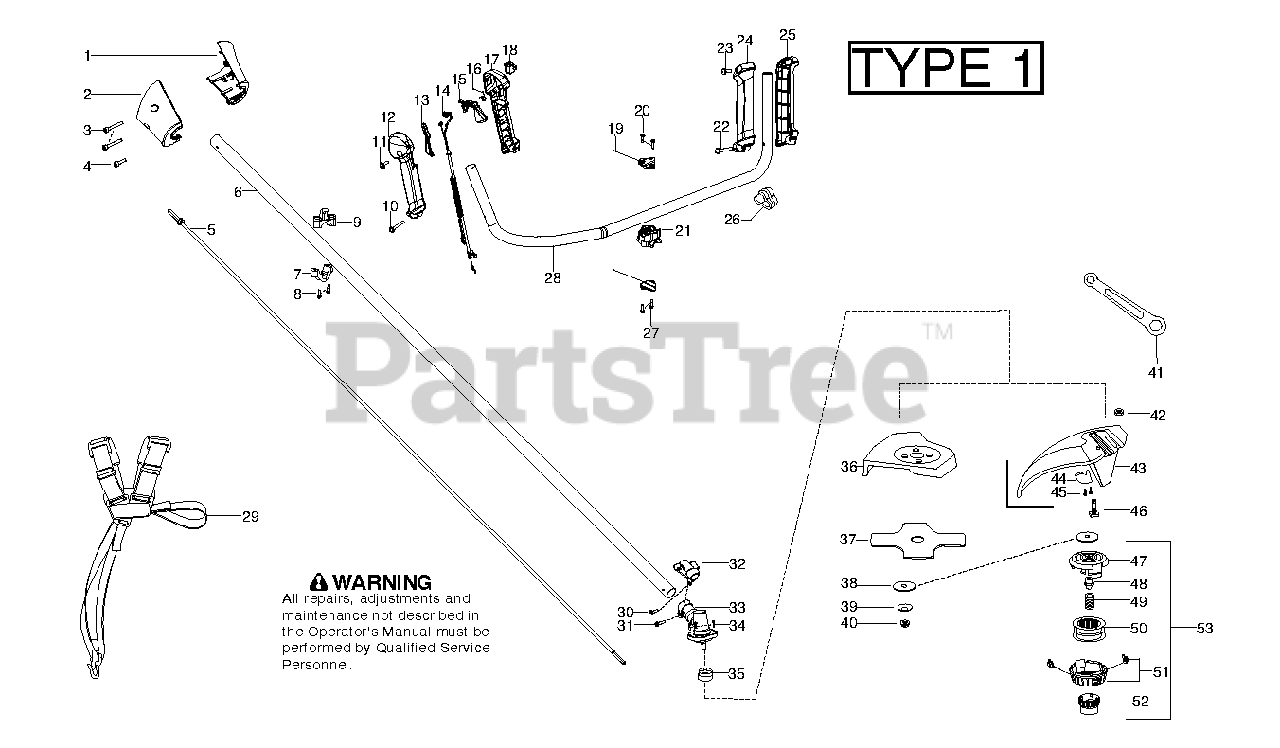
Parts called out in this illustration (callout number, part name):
1	NOSECONE LH LT33 BUL
2	NOSECONE RH LT33 BUL
3	SCREW M4 X 1.75 PT 16MM
4	SCREW-10-16 X 1/2, TYPE 2
5	FLEXSHAFT 57"
6	Drive Shaft Assembly
7	CLAMP HARNESS LOWER
9	CLAMP HARNESS UPPER
10	SCREW #10 PLASTITE 1.362
12	HANDLE HOUSING
13	THROTTLE LOCKOUT
19	CLAMP BRACKET
20	SCREW-10-14 X 13/16 (PL
22	SCREW #10 PLASTITE 1.362
28	ASSY HANDLEBAR BULLH
29	HARNESS BLACK NO LABEL
30	SCREW 8-16 X 9/16 (PLAS
31	SCREW - CARB. ADAPTOR
34	SCR 10-24 MS LDK PAN PH
35	DUST CUP , BLADE
36	KIT
37	ASSEMBLY
38	WASHER,BLADE RETAINING
39	Belleville Washer
40	NUT-FLANGE (LH)
49	SPRING
50	SPOOL WOUND LH 15 FT.
52	KNOB
53	Trimmer Head, P25
